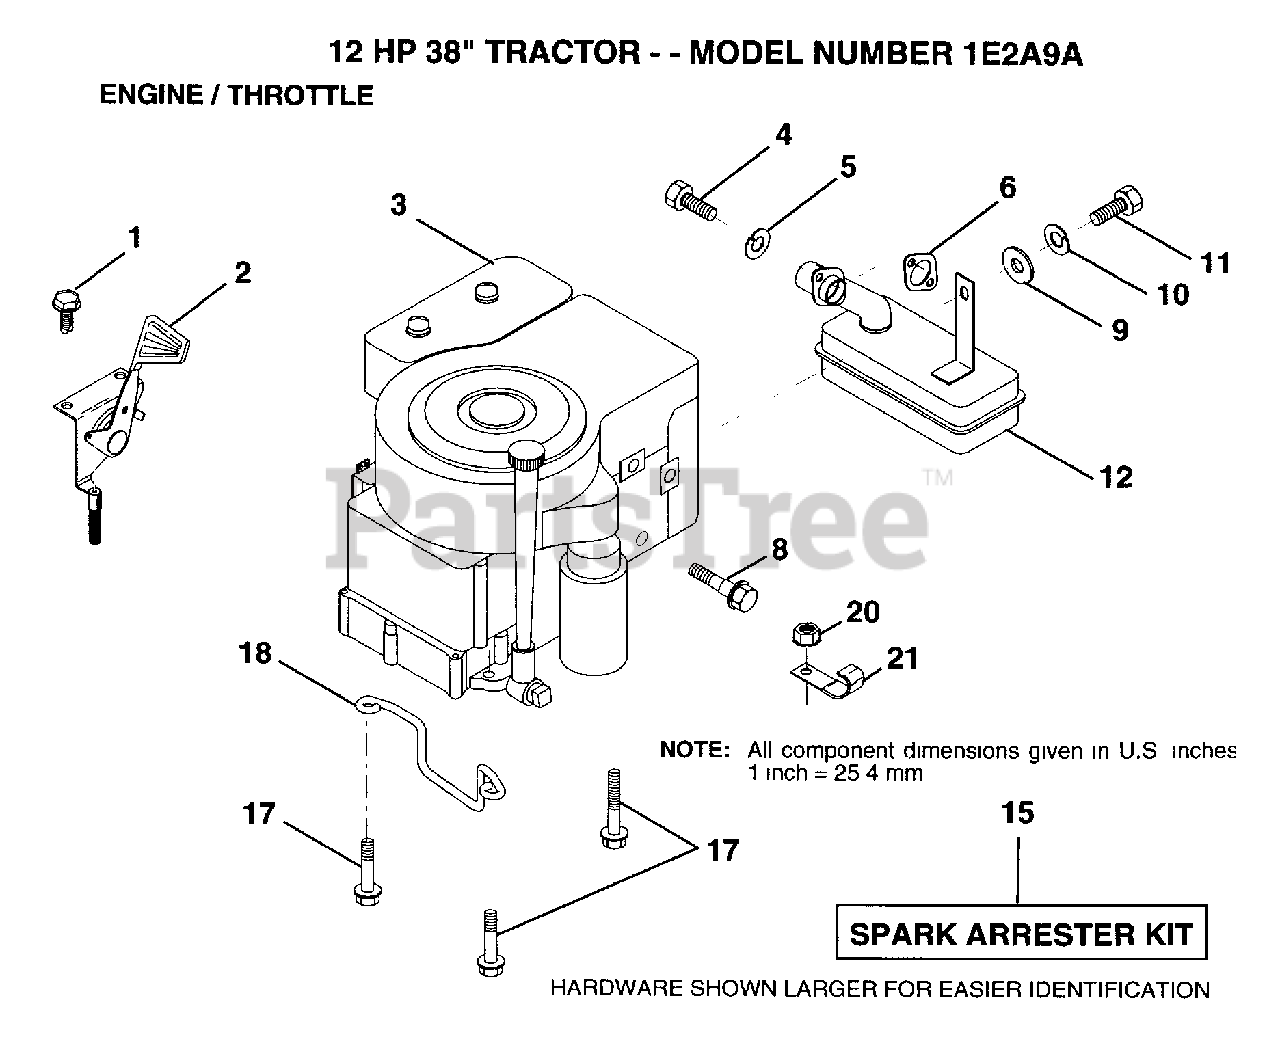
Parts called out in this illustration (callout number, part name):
1	SCREW.1/4-20X1/2
2	THROTTLE CONTROL
4	SCREW
5	LOCKWASHER
8	BOLT T
10	LOCKWASHER
12	MUFFLER
17	SCREW LT
18	"KEEPER,DR BELT GR"
20	NUT
21	CLIP T
